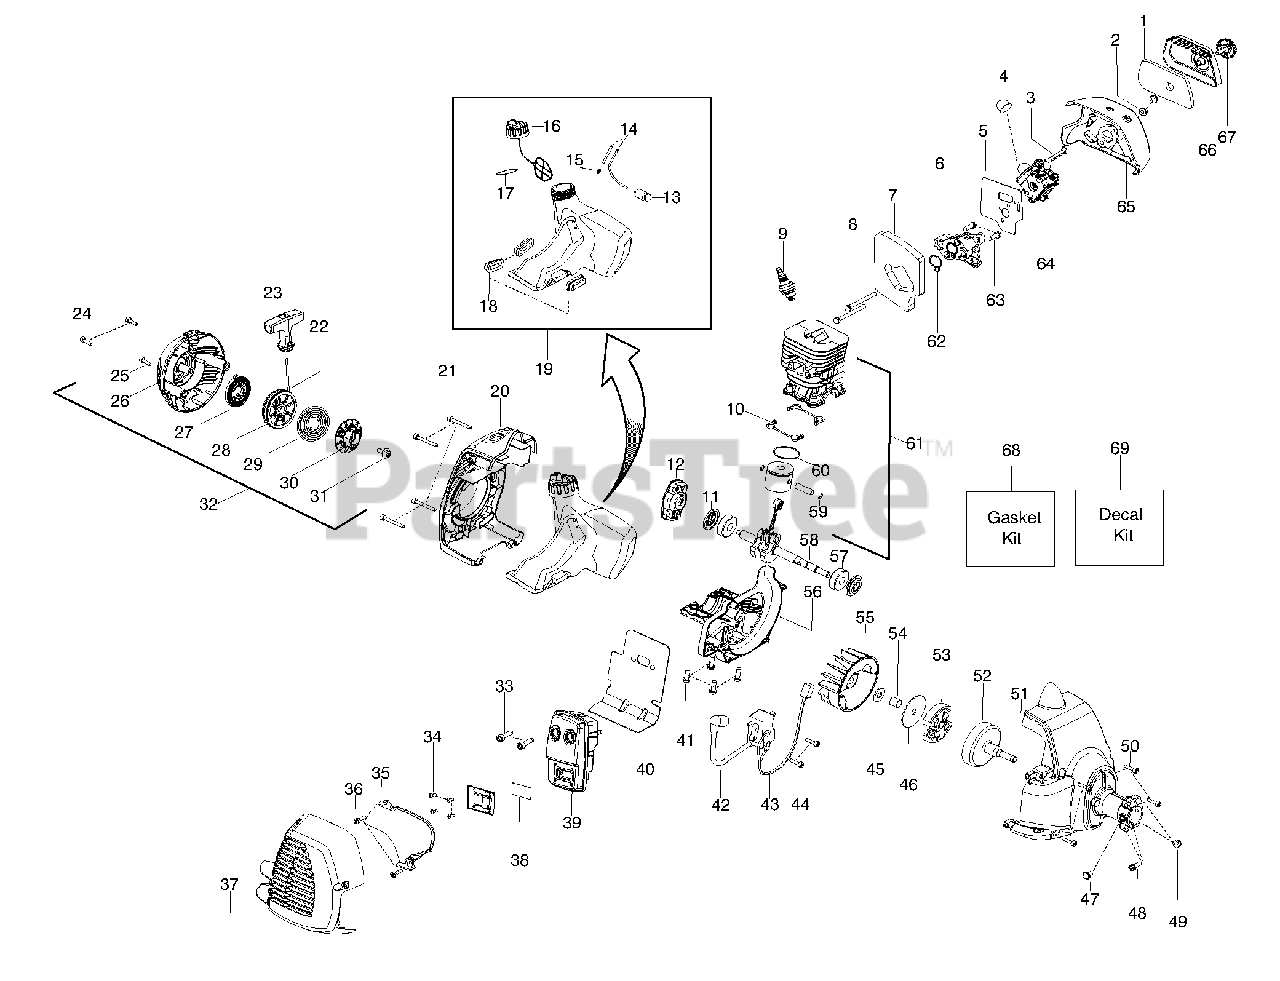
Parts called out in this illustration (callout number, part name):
2	Nut-Carb. Screw
3	Lever - Choke
4	Bulb-Purge
5	Kit-Carb. Gasket
6	Adaptor-Carb.
7	Foam-Gasket (kit)
9	Plug-Spark (RCJ-6Y)
10	Seal-Cylinder (kit)
11	Seal-Crankshaft (kit)
12	Assy-Starter Pawl
13	Assy-Fuel Filter
14	Kit-Fuel Line
15	Fitting-Fuel Line
16	Assy-Cap w/ret.
17	O-ring - Fuel Cap (kit)
18	Isolator-Tank
19	Kit-Fuel Tank Assy.
20	Shroud-Rear (KIT)
22	Kit-Rope
23	Handle-Starter
26	Starter Hsg. (KIT)
27	Kit-Spring
28	Kit-Starter Pulley
29	Spring - Driver
30	Pulley-Driver
32	Assy-Starter Hsg.
33	Bolt-Muffler
34	Screw
35	Shield-Heat
37	Kit - Muffler Guard
38	Kit-Spark Arrestor
39	Kit-Muffler
40	Gasket-Paper Met.(kit)
42	Module
43	Assy-Leadwire
46	Washer-Clutch
47	Screw
48	Screw
51	Assy-Fan Housing
52	Assy-Clutch Drum
53	Assy-Clutch
56	Crankcase-Cast
58	Assy-Crankshaft
59	Retainer-Piston Pin
60	Ring-Piston
61	Kit-Piston/Cyl.
62	Seal-adaptor (kit)
64	Kit-Carb.
65	Air box
66	Cover-Air Box
68	Kit-Gasket
69	Kit - Decal
